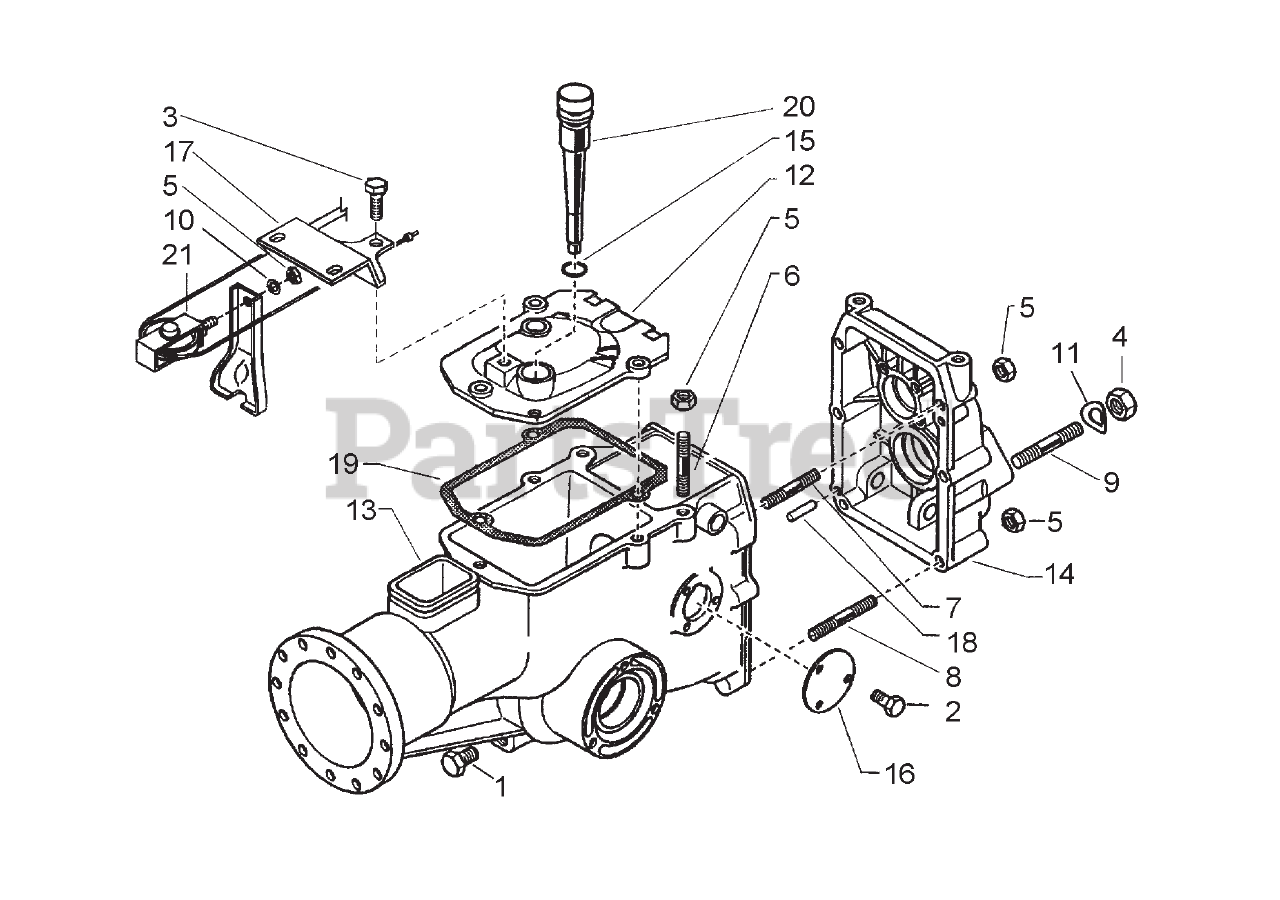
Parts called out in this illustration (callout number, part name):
2	SCREW
3	CAP SCREW
4	NUT, M12X1.25
5	NUT, SELF LOCKING, M8
6	STUD, M8X38X14X20
7	STUD, M8X56X20X12
8	STUD, M8X68
9	STUD, M12X1.25X12X64
10	SUPER WASHER, M8
11	WASHER, DOME, M13 ***
12	GEARBOX COVER
13	GEAR BOX CASE
14	REAR COVER
15	O RING
16	SIDE COVER
17	PLATE
18	PARALLEL PIN
19	GASKET, COVER
20	CAP WITH DIP STICK
21	PULLEY ASSEMBLY
